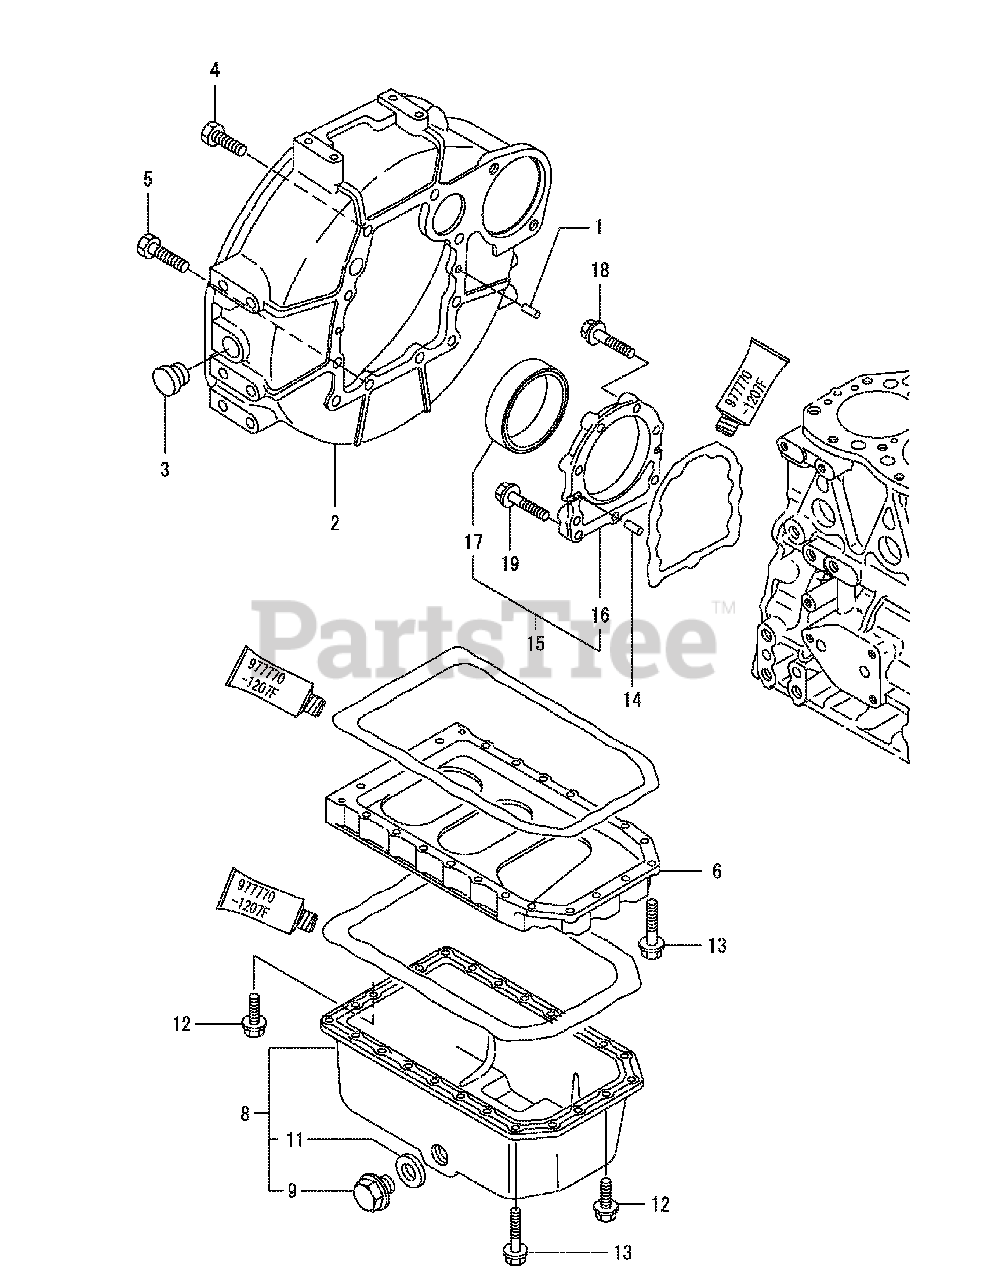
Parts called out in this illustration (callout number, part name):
1	Parallel Pin, M8 x 16
2	Flywheel Housing
3	Flywheel Cover Cap
4	Bolt, M10 x 25
5	Bolt, M10 x 30
6	Oil Sump Spacer
8	Oil Sump Assembly
9	Drain Plug, M22
14	Parallel Pin, M8 x 16
15	Oil Seal Case Assembly
16	Oil Seal Case
